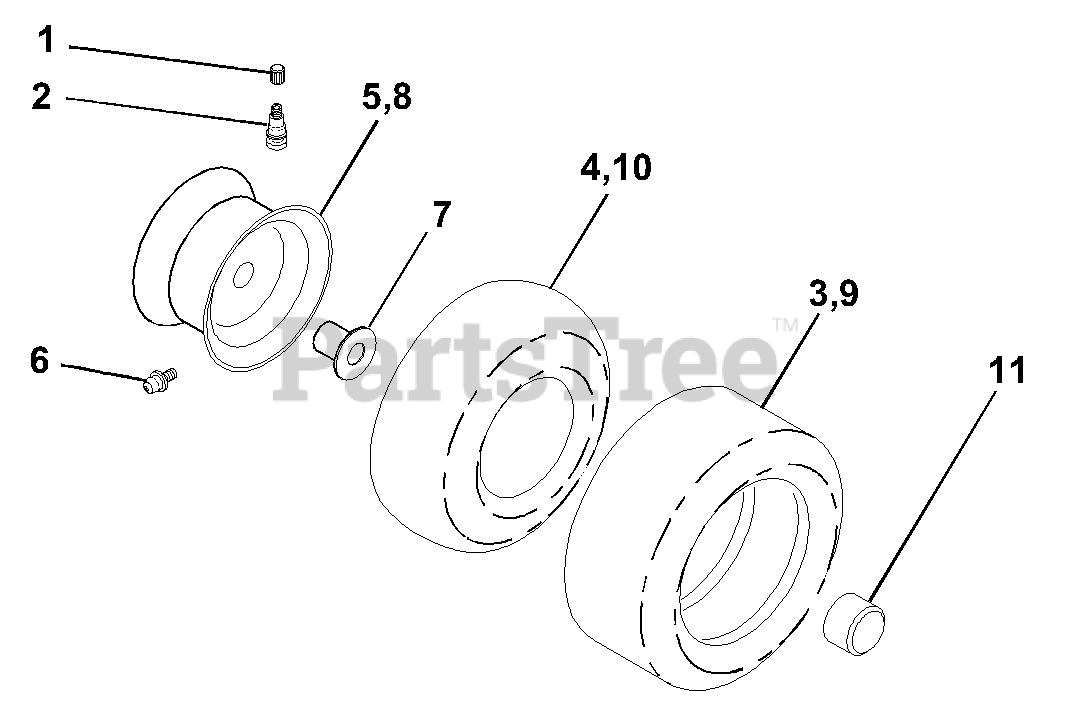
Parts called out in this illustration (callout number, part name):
1	Cap Valve Tire
2	Stem Valve
3	Tire F Ts 15 X 6 0 - 6 Service
4	Tube Front
5	Rim Asm 6" front Service
6	Fitting Grease
7	Bearing Flange
8	Rim Asm 8" rear Service
9	Tire R Ts 20 x 10 -8 C Service
10	Tube Rear
11	Cap Axle Blk 1 50 X 1 00
